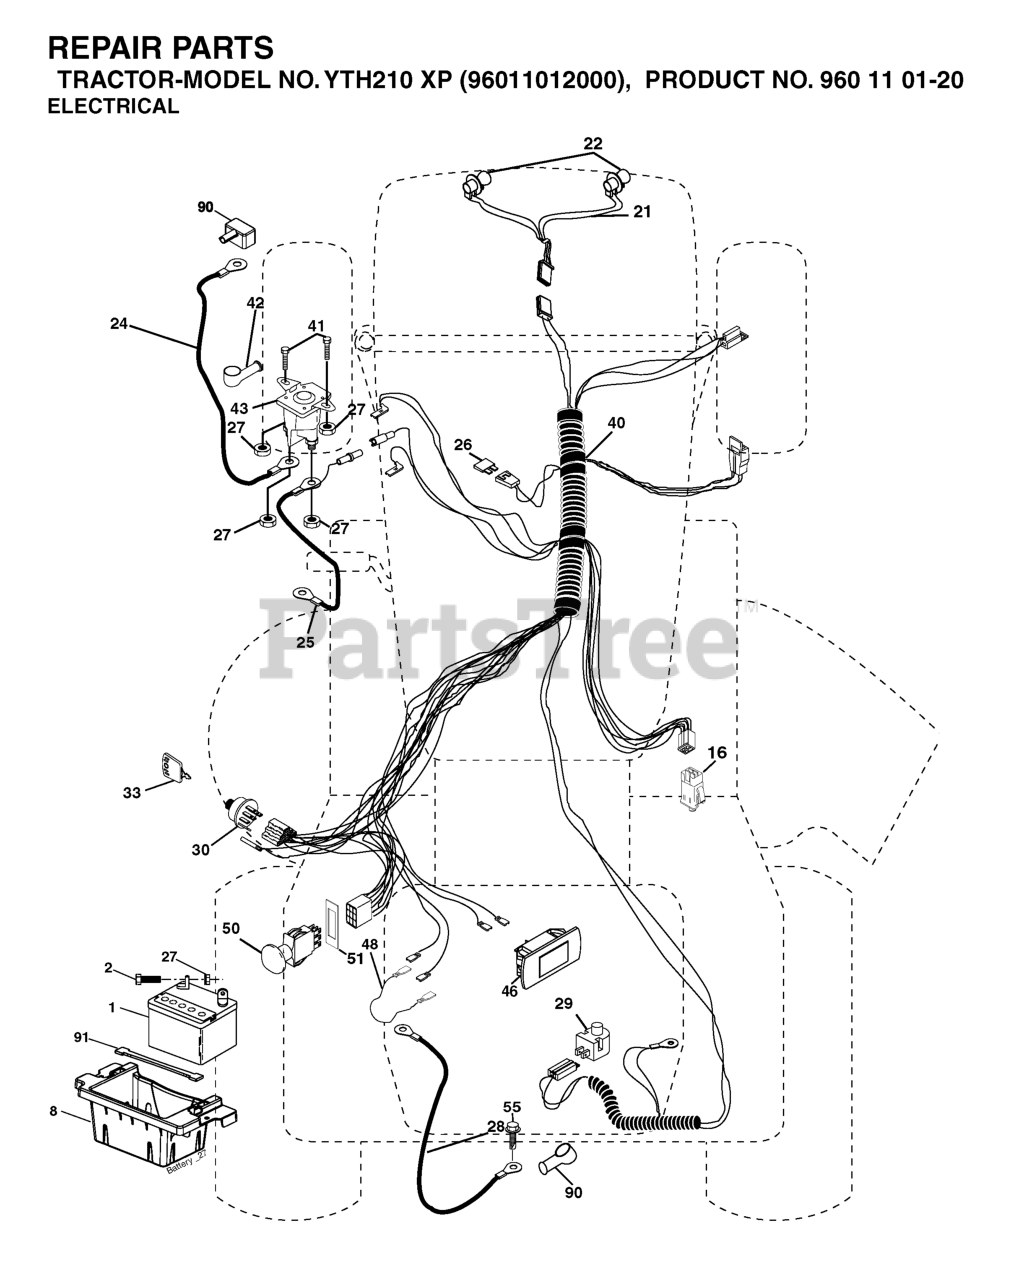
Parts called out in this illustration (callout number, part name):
1	BATTERY 12V .35 AMP
2	BOLT.HEX.1/4.X.3/4.DICHROMATE
8	BOX.BATTERY.MOUNT.FRONT.LT
16	SWITCH INTERLOOK PUSH-IN
21	HARNESS.W/LIGHT SOCKET
24	BATTERY CABLE GT
25	CABLE BATTERY 6 GA 22" W/16W
26	FUSE 20AMP
27	NUT
28	CABLE GROUND 6 GA 21" 90T BLK
29	SWITCH.SEAT.DP W/RAMPS
30	SWITCH.IGN.DELTA.W.LGH.ROS
33	KEY MLD GEN DELTA
40	HARNESS.IGN.ELEC.STL.N/RELY.05
41	BOLT
42	TERMINAL COVER
43	SOLENOID.W/BRASS.PLUNGER
46	GAUGE.SERVICEMINDER.HR
48	ADAPTER.AMMETER
50	RP.PTO.SWITCH.8 TERMINAL.BLACK
51	FRAME RETAINING RING
55	Screw 5/16-18 x 1/2 Hex, Self Tapping 5/16-18 x 1/2
90	COVER TERMINAL
91	STRAP.BATTERY.MOUNT.FRONT(2 2)
